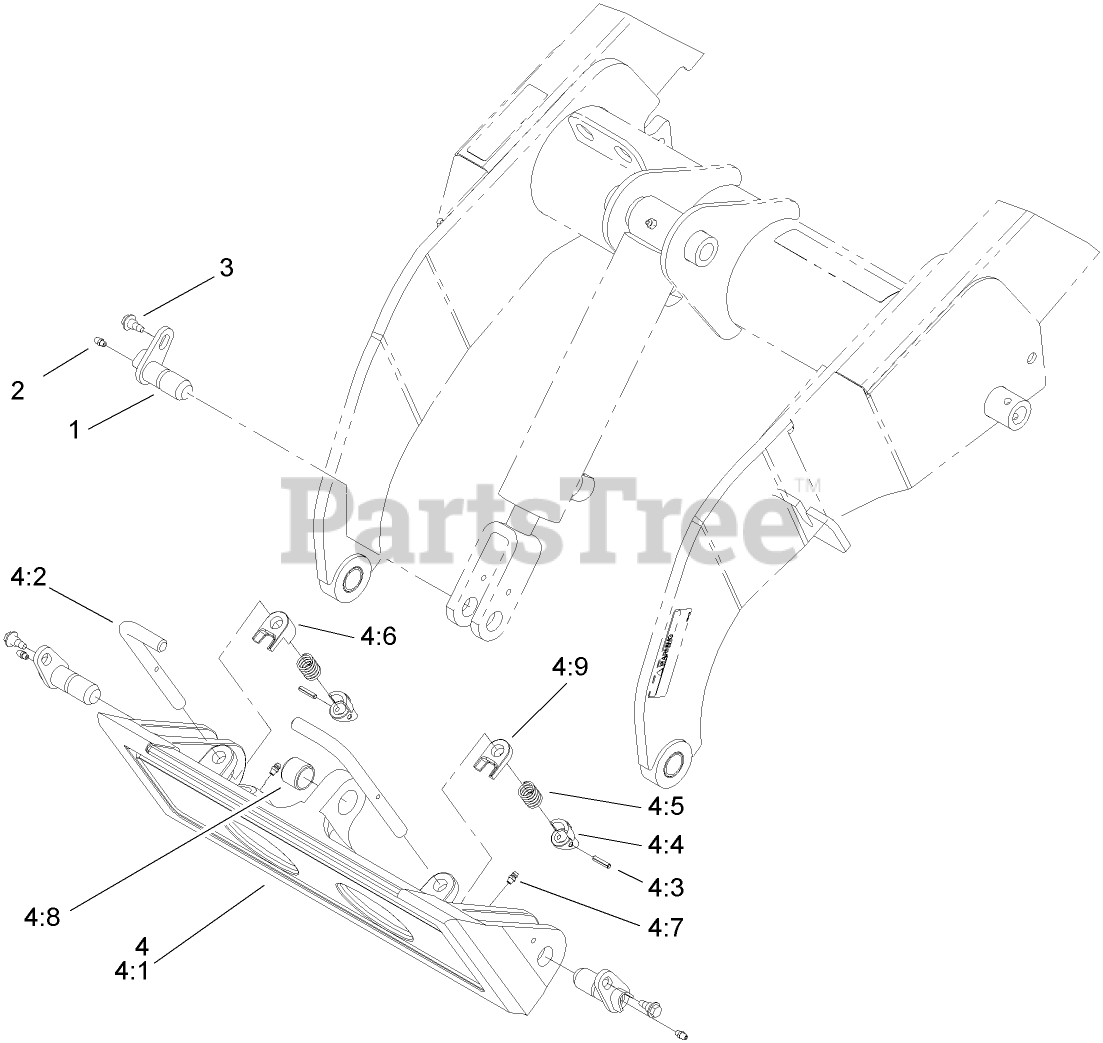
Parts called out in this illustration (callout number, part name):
1	PIN-PIVOT
2	FITTING-GREASE
3	BOLT-SHOULDER
4	QUICK ATTACH ASM
4:1	MOUNT-ATTACH, QUICK
4:2	PIN-LOCKING
4:3	PIN-GROOVED
4:5	SPRING-COMPRESSION
4:6	STOP-RH
4:7	FITTING-GREASE
4:8	BUSHING-TENSION
4:9	STOP-LH
